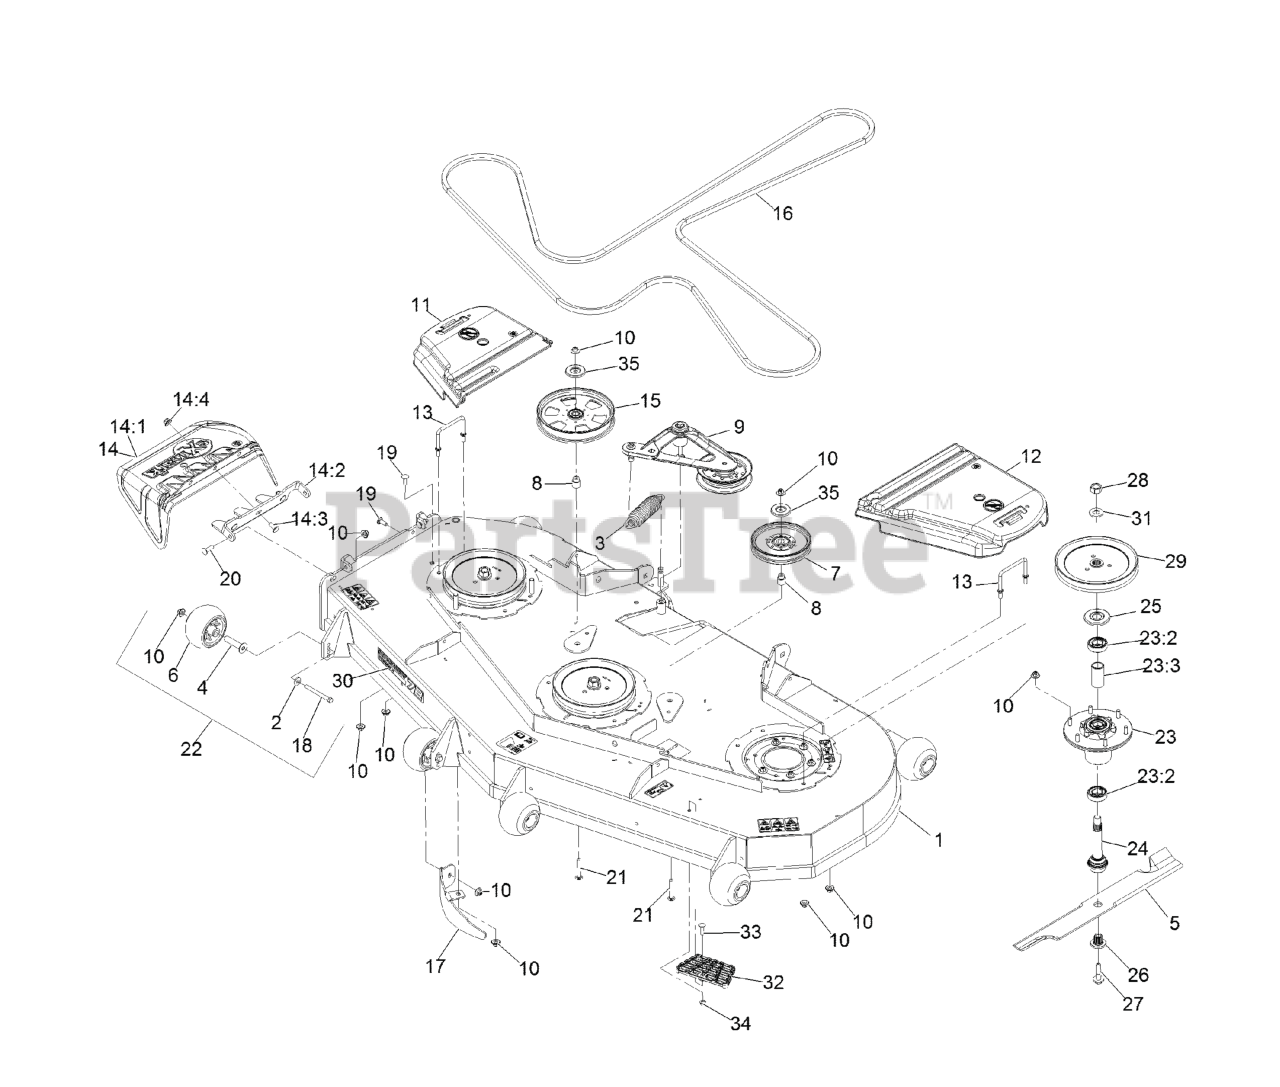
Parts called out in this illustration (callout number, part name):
1	ASM,DECK W/DECALS 724
2	WASHER-BELLEVILLE
3	SPRING-EXTENSION
4	AXLE, ROLLER
6	ROLLER-SCALP, ANTI
7	IDLER-PULLEY
8	BUSHING-IDLER
9	DECK IDLER ASM
10	Nut-Nyloc 3/8-16 Flg
11	COVER-BELT, RH
12	COVER-BELT, LH
13	WIREFORM-COVER
14	ASM,DISCHARGE CHUTE
14:1	CHUTE,DISCHARGE
14:2	BRACKET,DISCHARGE CHUTE
14:3	SCREW-CARR
14:4	Nut-Nyloc 3/8-16 Flg
15	PULLEY-IDLER, FLAT
17	BAFFLE-DOGLEG, LZ72
18	SCREW-HH 3/8-16 X 3 3/4 GR 8
19	SCREW-CARR
20	Bolt-Carriage 3/8-16 X 1 1/4
21	SCREW-CARR
22	KIT, ANTI-SCALP ROLLER
23	ASM-CUTTER HSG WITH BEARINGS
23:2	BEARING-BALL
23:3	SPACER-BEARING
24	ASM-SPINDLE AND SEAL
25	GUARD,BEARING TOP .989
26	BUSHING,SPLINED
27	SCREW,SEMS 1/2-20 X 2.19
28	NUT-HEX
29	SHEAVE,BLADE DRIVE 8.74
30	DECAL, 724
32	STEP-DECK
33	Bolt-Carriage 5/16-18 X 1 1/4
34	NUT-HF, NI
35	SHIELD-DUST
